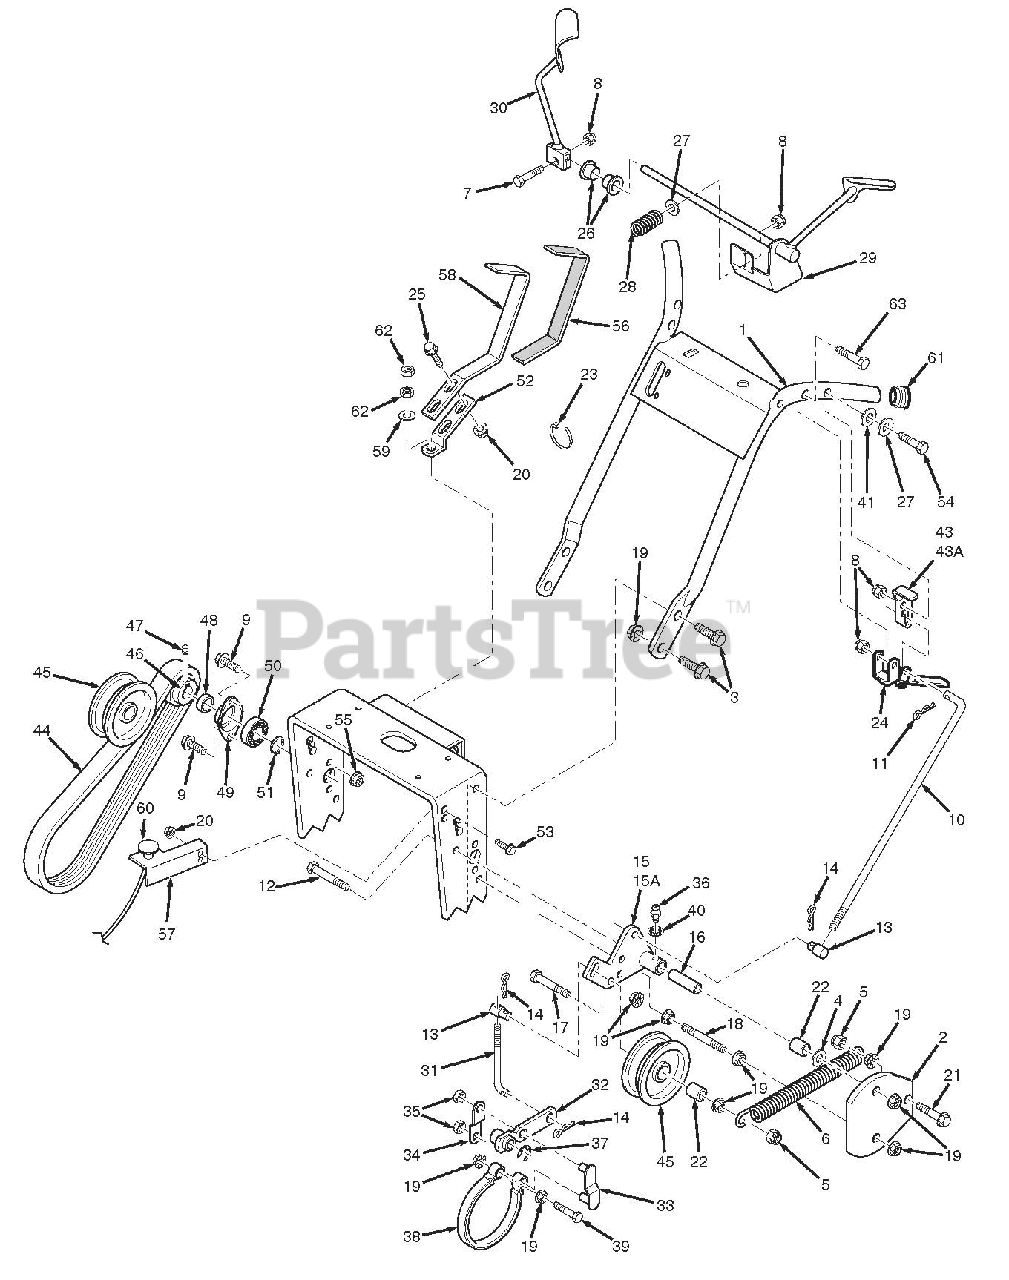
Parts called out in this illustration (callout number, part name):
1	Handle Assembly
2	Belt Guard
3	Capscrw, 3/8-16 x 1" Serr. Flg.
4	Washer, 3/8" (.391 x .938 x .105)
5	Nut, 3/8-16 Elastic Stop
6	Spring, Idler
7	Bolt, 5/16-18 x 1-1/4" Hex Head
8	Nut, 5/16-18 Elastic Stop
9	Capscrew, 1/4-20 x 3/4" Hex Head
10	Control Rod, Steering
11	Hair Pin, Small
12	Bolt, 3/8-16 x 4-1/2" Hex Head
13	Swivel Joint
14	Hair Pin, Large .094 Dia.
15	Idler Bracket, RH
15A	Idler Bracket, LH
16	Idler Sleeve
17	Bolt, 3/8-16 x 3/4" Hex Head
18	Stud, 3/8-16 x 5"
19	Nut, 3/8-16 Serrated Flange
20	Nut, 5/16-18 Serrated Flange
21	Cpscrw, 3/16-18 x 1-1/4" Serr. Flg
22	Spacer
23	Cable Tie
24	Steering Lever
25	Capscrew, 5/16-18 x 1" Serr. Flg.
26	Bushing
27	Washer, 5/16 (.375 x .875 x .083)
28	Spring, Operator Presence
29	Operator Presence Lever, LH
30	Operator Presence Lever, RH
31	Brake Rod
32	Brake Lever
33	Brake Link
34	Brake Link Plate
35	Nut, 3/8 Push-on
36	Grease Fitting, Straight 1/4-28
37	Retaining Ring, 5/8 Ext. "E"
38	Brake Band
39	Bolt, 3/8-16 x 2" Hex Head
40	1/4" Internal Tooth Lockwasher
41	Socket Head Capscrew #8-32 x 1/2"
42	Socket Head Capscrew #8-32 x 1/2"
43	Neutral Latch, RH
43A	Neutral Latch, LH
44	Belt, Wheel Drive
45	Idler Pulley, Wheel Drive
46	Pulley, Jackshaft
47	Setscrew, Hex Socket Knurl Cup Pt. 5/16-18
48	Spacer, Jackshaft Pulley
49	Flange, Jackshaft Bearing
50	Bearing, Jackshaft
51	Retaining Ring, 5/8 Ext. Basic
52	Shift Lever
53	Capscrew, 5/16-18 x 3/4" Serr. Flg.
54	Bolt, 5/16-18 x 2" Hex Head
55	Nut, 1/4-20 Serrated Flange
56	Grip, Shift Handle
57	Bracket, Choke Mounting
58	Shift Lever Extention
59	Washer, 3/8 (.391x .938 x .105)
60	Choke Control
61	Plug, Handlebar
62	Nut, 3/8-24 UNF
63	Bolt, 5/16-18 x 2-1/2"
64	Fuel Tank Cap
